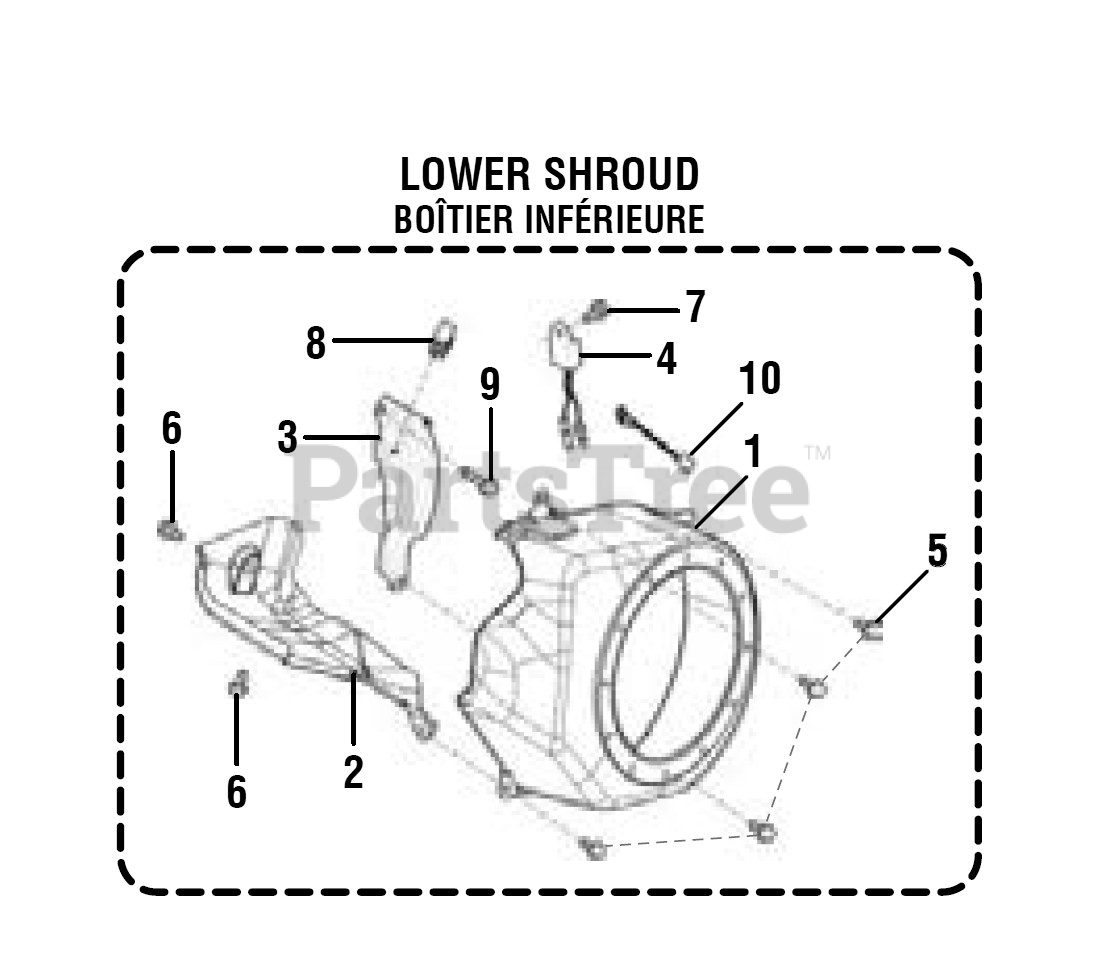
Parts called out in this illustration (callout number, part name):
2	Cylinder Body Shroud
3	Lower Shield
4	Oil Protector
8	Collar
10	Engine Stop Wire
